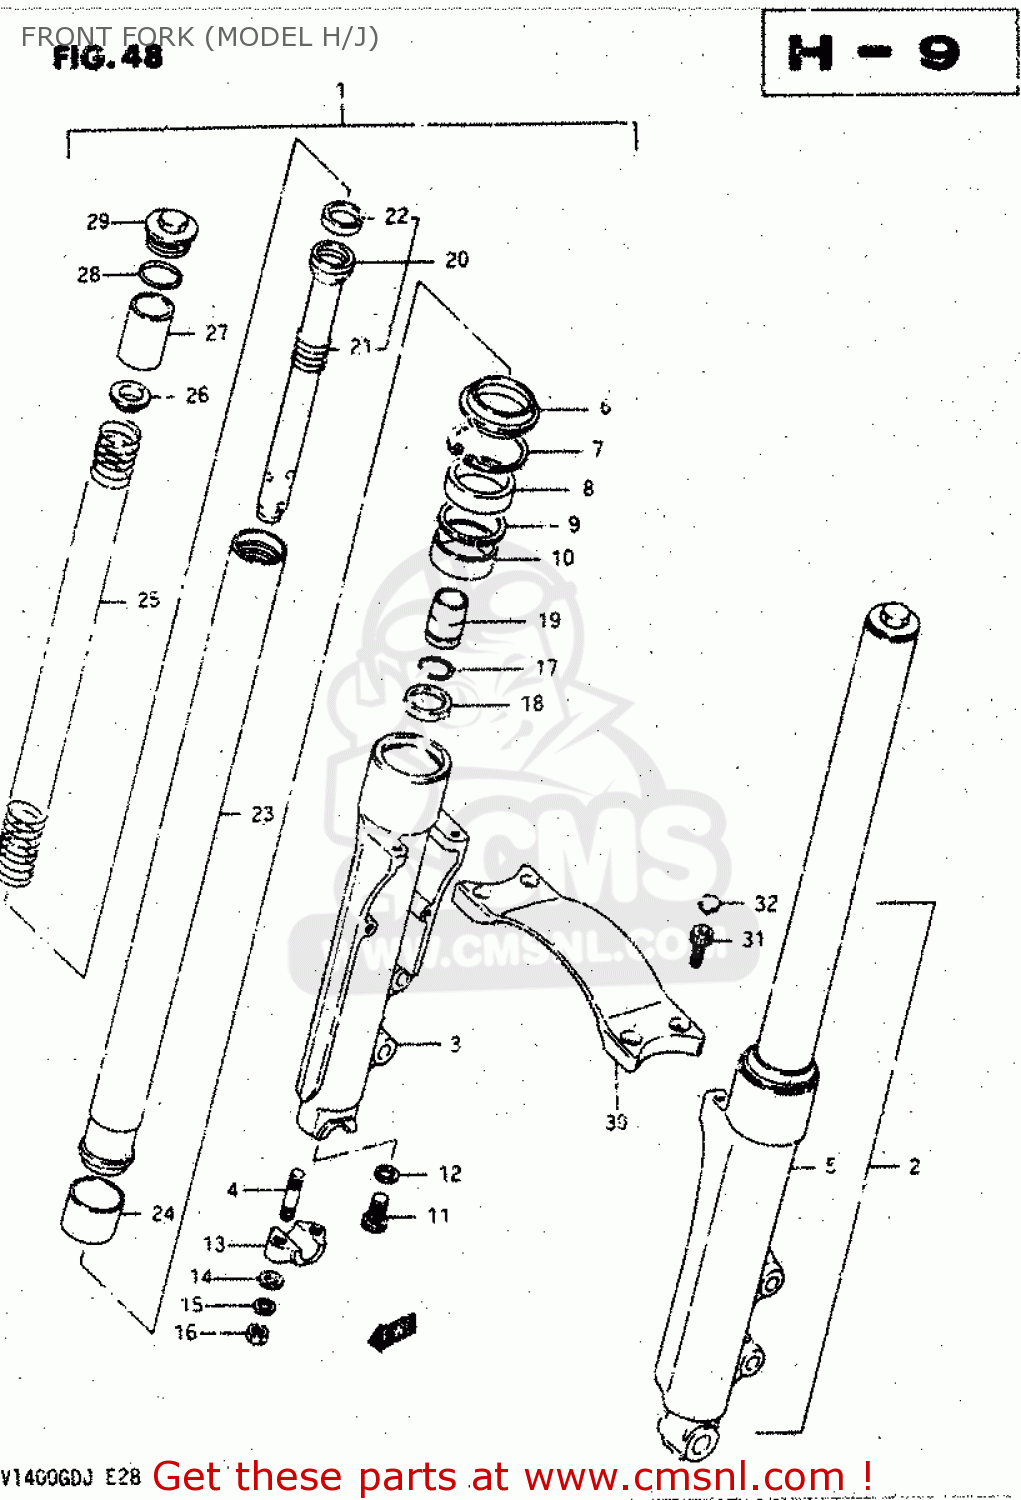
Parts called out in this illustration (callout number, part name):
1	DAMPER ASSEMBLY,RIGHT
2	DAMPER ASSEMBLY,LEFT
3	TUBE,OUTER,RIGHT
4	STUD 8X30
5	TUBE,OUTER,LEFT
6	DUST SEAL,FRONT FORK
7	RING,OIL SEAL STOPPER
8	OIL SEAL,FRONT FORK
9	WASHER,FORK OIL SEAL
10	METAL,SLIDE
11	BOLT,CYLINDER
12	GASKET,CYLINDER (NAS)
13	HOLDER,AXLE
14	WASHER
15	WASHER,LOCK,8.
16	NUT (8MM)
17	RING,SNAP
18	VALVE
19	PIECE,OIL LOCK
20	CYLINDER
21	SPRING,REBOUND
22	RING,PISTON
23	TUBE,INNER
24	METAL,SLIDE FR FORK
25	SPRING
26	GUIDE,SPRING
27	SPACER,SPRING
28	O RING
29	BOLT,FORK
30	BRACE,FORK
31	BOLT
32	CAP(OD:14.5)
